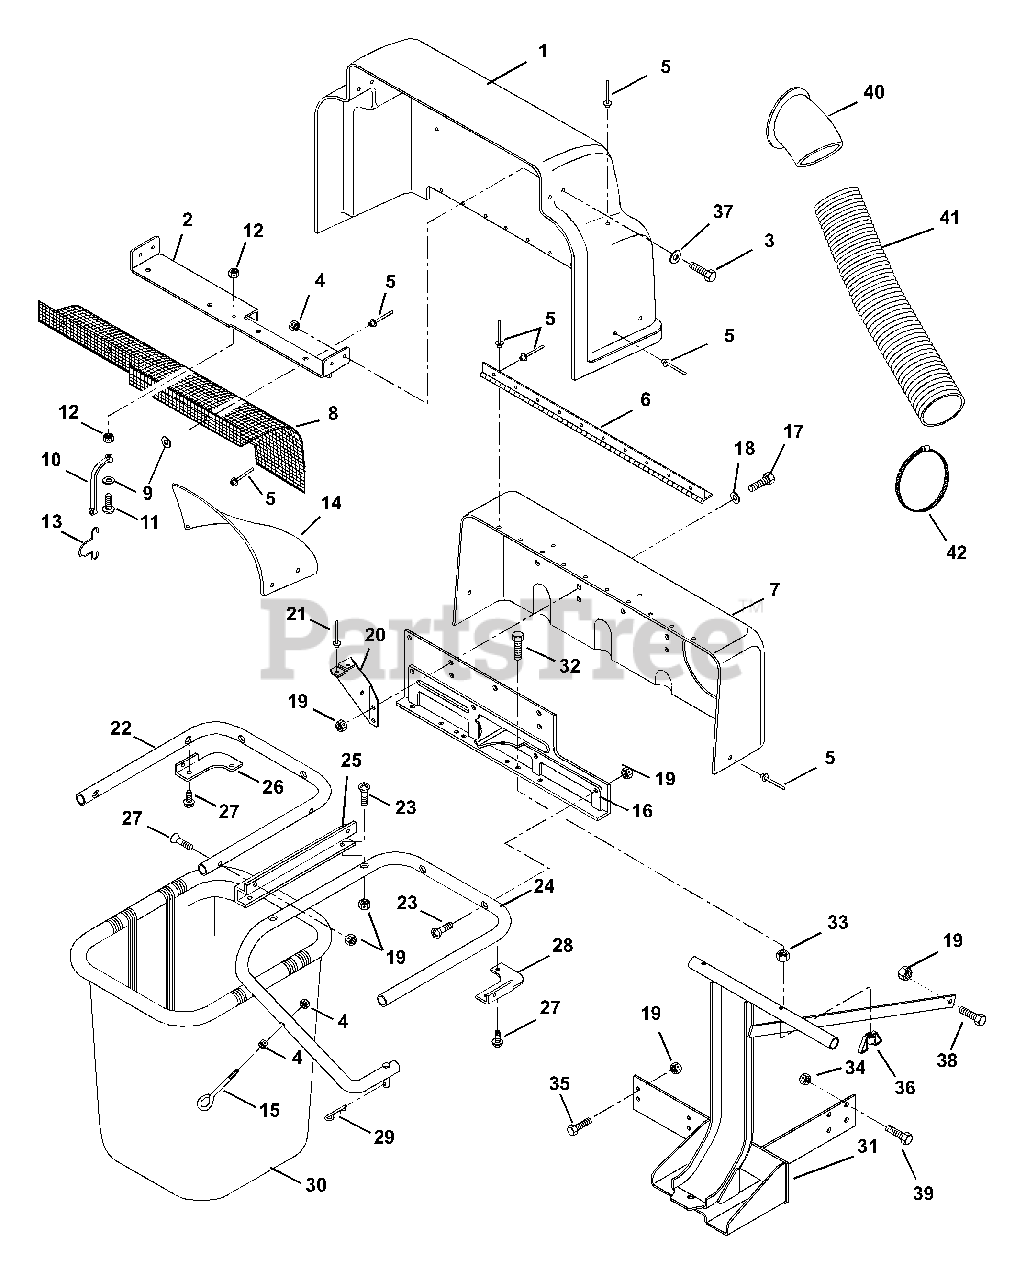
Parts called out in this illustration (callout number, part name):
1	HINGED COVER
2	COVER BRACKET
3	@BLT-HEX .25-20X.50 GR5 YWZC
4	@NUT-LK-CTR .25-20 YWZC
5	RVT-POP .187X.402 DOME ST
7	STATIONARY COVER
8	SCREEN, BAGGER
9	@WSHR-FL-STL.219X.50X.049 YWZC
10	BATTERY STRAP
11	SCR-MCH 10-24X.88 SLRH YWZC
12	@NUT-LK-NYL 10-24 W/INSRT YWZC
15	EYEBOLT
16	MOUNTING BRACKET
17	BOLT-HEX.31-18X.875 YWZC GR5
18	WSHR-FL-STL .328X.875X.062YWZC
19	@NUT-LK-CTR .31-18 YWZC
21	RVT-POP.187X.527 DOME ST
22	CENTER TUBE
23	SCR-MCH .31-18 X 1.50 YWZC
24	RIGHT TUBE
25	TUBE BRACKET
26	LH CORNER BRACKET
27	@SCR-TAP .31-18X.50 HWH TR YWZ
28	RH CORNER BRACKET
29	PIN-HAIR INT .08X.38X1.42 YWZC
30	GRASS BAGGER BASKET
31	FRAME, BAGGER
32	BLT-HEX .31-18X1.75 FLTHD YWZC
33	@NUT-HEX .31-18 YWZC
34	@NUT-LK-CTR .38-16 YWZC
35	@BLT-HEX .31-18X1.00 GR5 YWZC
36	NUT-NYLK WING .312-18 YWZC
37	@WSHR-FL-STL.281X.62X.065 YWZC
38	@BLT-HEX .31-18X.75 GR5 YWZC
39	@BLT-HEX .38-16X1.00 GR5 YWZC
40	BAGGER BOOT - UPPER
41	HOSE 7 X 45
42	CLAMP-HOSE WRM 2.13/8.62X.56
